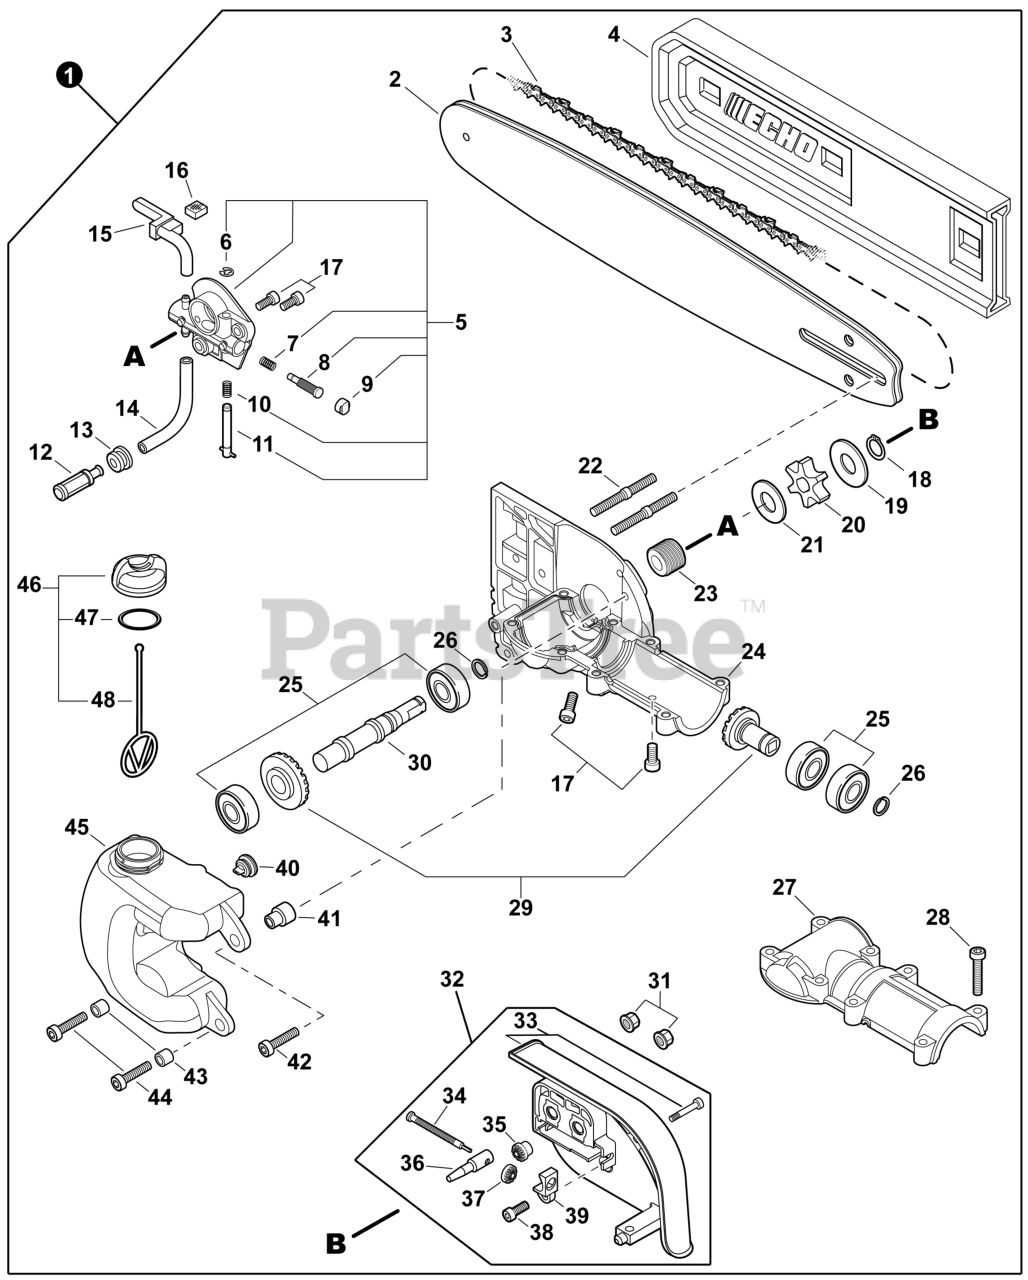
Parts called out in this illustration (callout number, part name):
1	CUTTING HEAD ASSY W/ B & C
2	GUIDE BAR, 10" 0.050" GA
3	SAW CHAIN 10" 0.050" GA
4	SCABBARD 10"
5	AUTO-OILER ASSY
8	PLUNGER ASSY
9	CAP, PLUNGER
11	ADJUSTER, OILER
12	FILTER, OIL
14	PIPE 3x6x70
15	PIPE, OIL OUTLET
16	PAD, FOAM
17	BOLT, TORX 5x10
18	RING, SNAP
19	WASHER 10
20	SPROCKET, DRIVE
21	WASHER 10.2x24.5x1.2
22	BOLT, STUD 6
23	GEAR, WORM
24	CASE, GEAR
25	BEARING, BALL
26	RING, SNAP 12
27	COVER, GEAR CASE
28	BOLT, TORX 5x25
29	GEAR SET
30	SHAFT, GEAR
31	NUT, FLANGE M6
32	SPROCKET GUARD ASSY
33	GUARD, SPROCKET
35	GEAR - 14 TOOTH
36	TENSIONER, CHAIN
37	GEAR - 14 TOOTH
38	SCREW 4
39	COLLAR 8
40	VENT ASSY
41	COLLAR 6
42	BOLT, TORX 5x25
43	SPACER 6.2x7.8x6
44	BOLT, TORX 5x20
45	TANK, OIL
46	CAP ASSY
47	O-RING 18
48	CONNECTOR, CAP L= 60 MM
